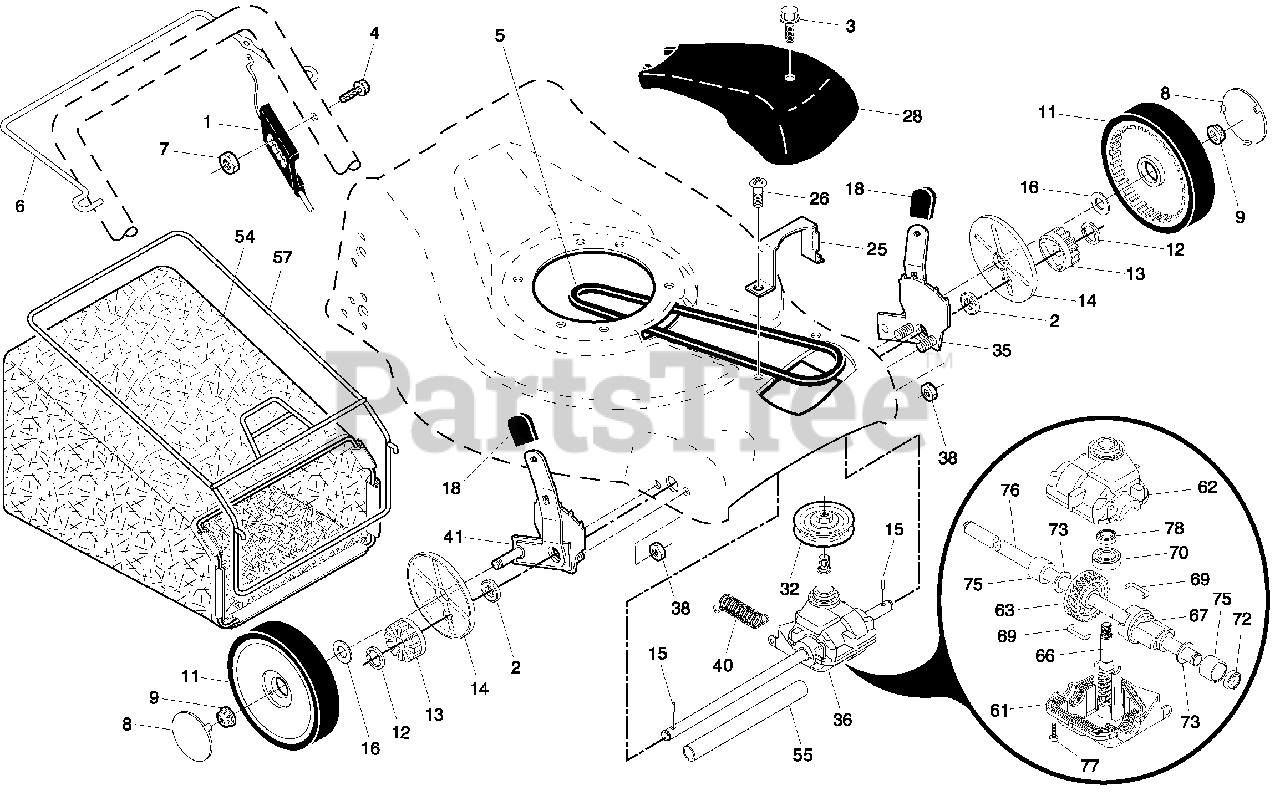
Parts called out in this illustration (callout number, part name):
1	Drive Control Assembly
2	Bearing, Wheel Adjuster
3	Pan Head Tapping Screw #10-24 x 2-3/4
4	Screw
5	V-Belt
6	Bar, Drive Control
7	Nut, Hex
8	Hubcap
9	Locknut
11	Wheel & Tire Assembly, Front, 8"
12	E-Ring
13	Pinion, Gear
14	Dust Cover
15	Pawl, Drive
16	Washer 1/2 x 1-1/2 x .134
18	Selector Knob
25	Belt Keeper
26	Screw
28	Drive Cover
35	Kit, Wheel Adjuster, LH
36	Gear Case Assembly, Complete
38	Locknut 1/4-20
39	Pulley, Drive
40	Spring, Return
41	Kit, Wheel Adjuster, RH
54	Grassbag Assembly
55	Driveshaft Cover
57	Frame, Grassbag
60	Case, Upper
61	Shaft, Output
62	Seal, Output Shaft
63	Bushing
64	Washer
65	Seal, Worm Shaft
66	Bearing, Ball
67	Gear, 28 Teeth
68	Fixed Dog Clutch
69	Pin
70	Movable Dog Clutch
71	Screw, Case
72	Case, Lower
73	Spring, Leaf
74	Shaft, Worm
